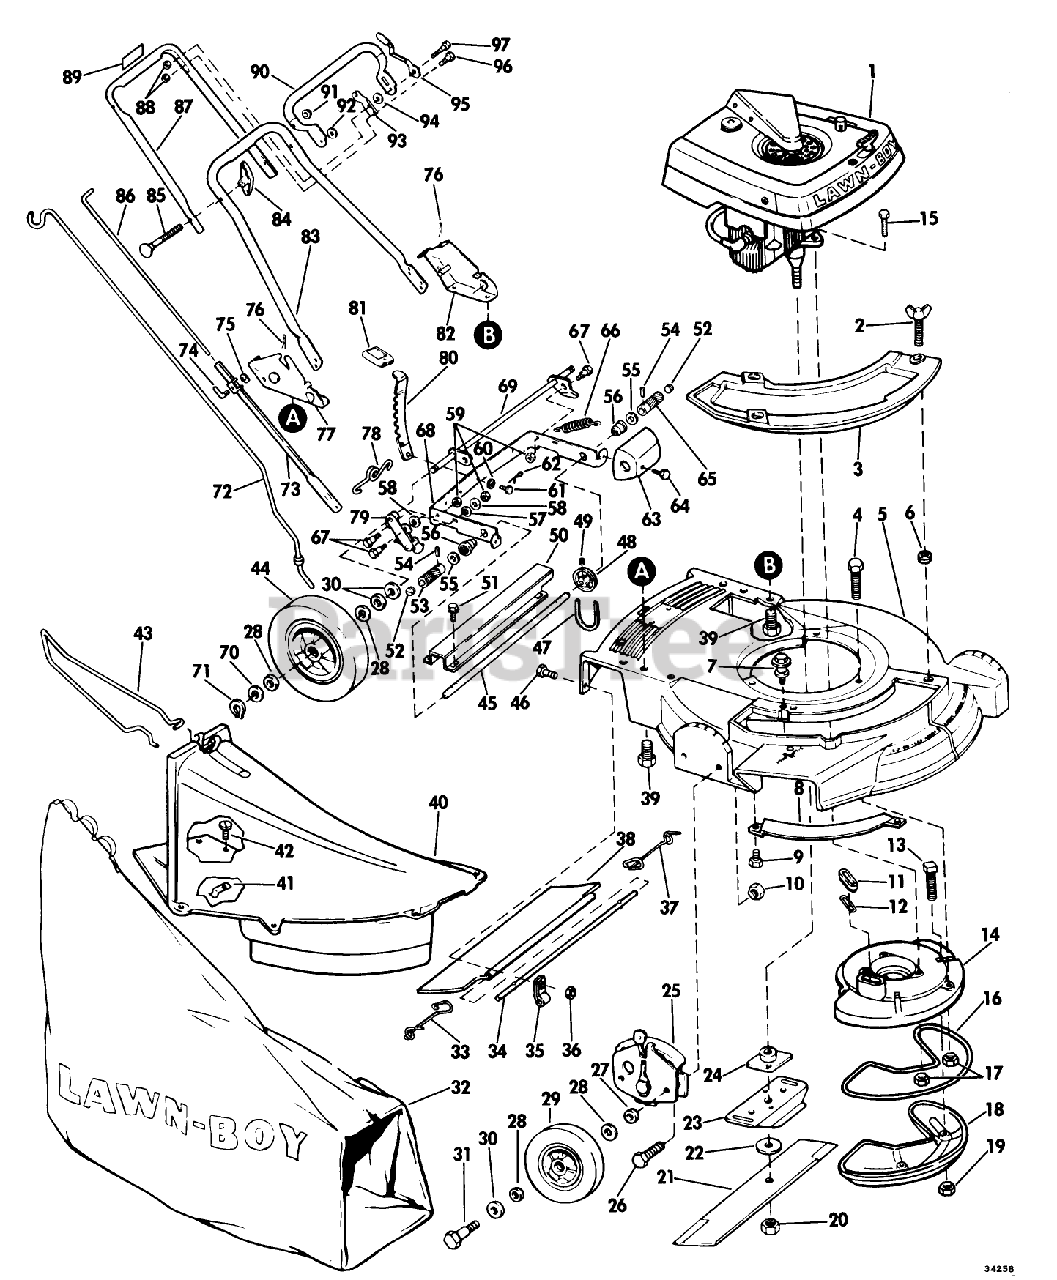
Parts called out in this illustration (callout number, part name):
2	WING SCREW LAWRE
4	SCREW
8	BAR-TOE
10	NUT
11	SLEEVE
12	GASKET S
17	NUT-LOCK F
20	NUT-BLADE
22	WASHER
24	PLATE AND COLLAR ASM
27	WASHER WROUGHT
28	WASHER
30	SPACER
31	BOLT WHEEL
32	89802 LB WHOLE GOODS
33	SPRING;TRAILING SHIELD RH
34	ROD 21" ADVANCE
35	CLAMP ROD KMC
37	SPRIG T/SHLD ASOC
39	SCREW
47	V-BELT
51	SCREW F
52	GREASE PLUG
54	PIN
58	WASHER S
59	STOP NUT
60	WASHER SPRING LAR
61	PIN
63	GUARD
66	SPRING
67	BOLT RB&W
70	SPACER
71	RET RING
72	ROD GRASSBAG
76	HAIR PIN
78	SPRING N.A.S
80	LEVER
81	KNOB
83	Cover Plate
85	SCREW
86	ROD CONTROL
92	WASHER M
95	KNOB & SPRING
97	BOLT RB&W
